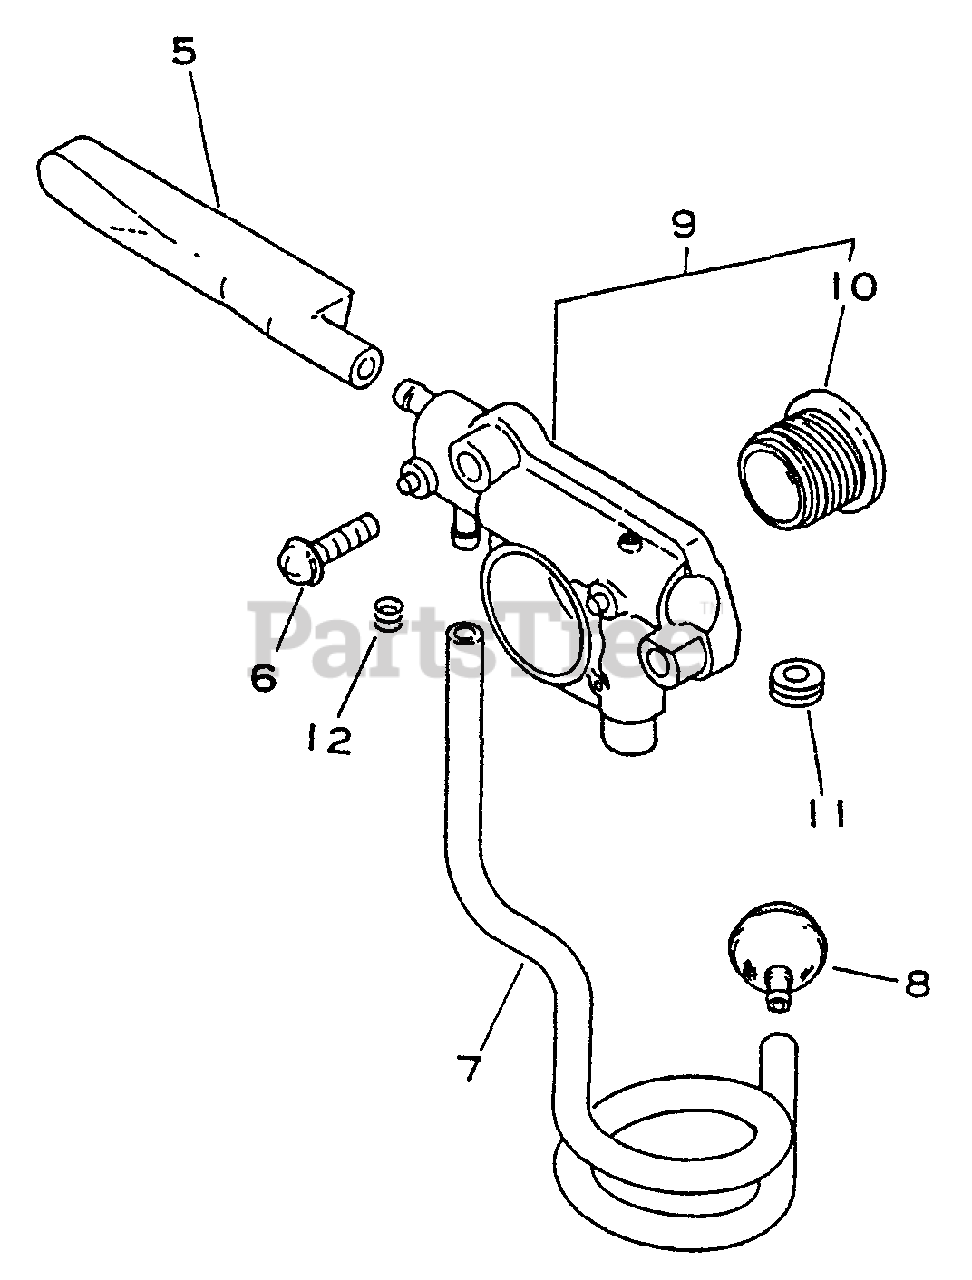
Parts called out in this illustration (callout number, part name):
5	PIPE, OIL
6	BOLT 4×16
7	PIPE, OIL
8	FILTER, OIL
9	AUTO-OILER ASSY
10	GEAR, WORM
12	CLIP 6.6 MM
